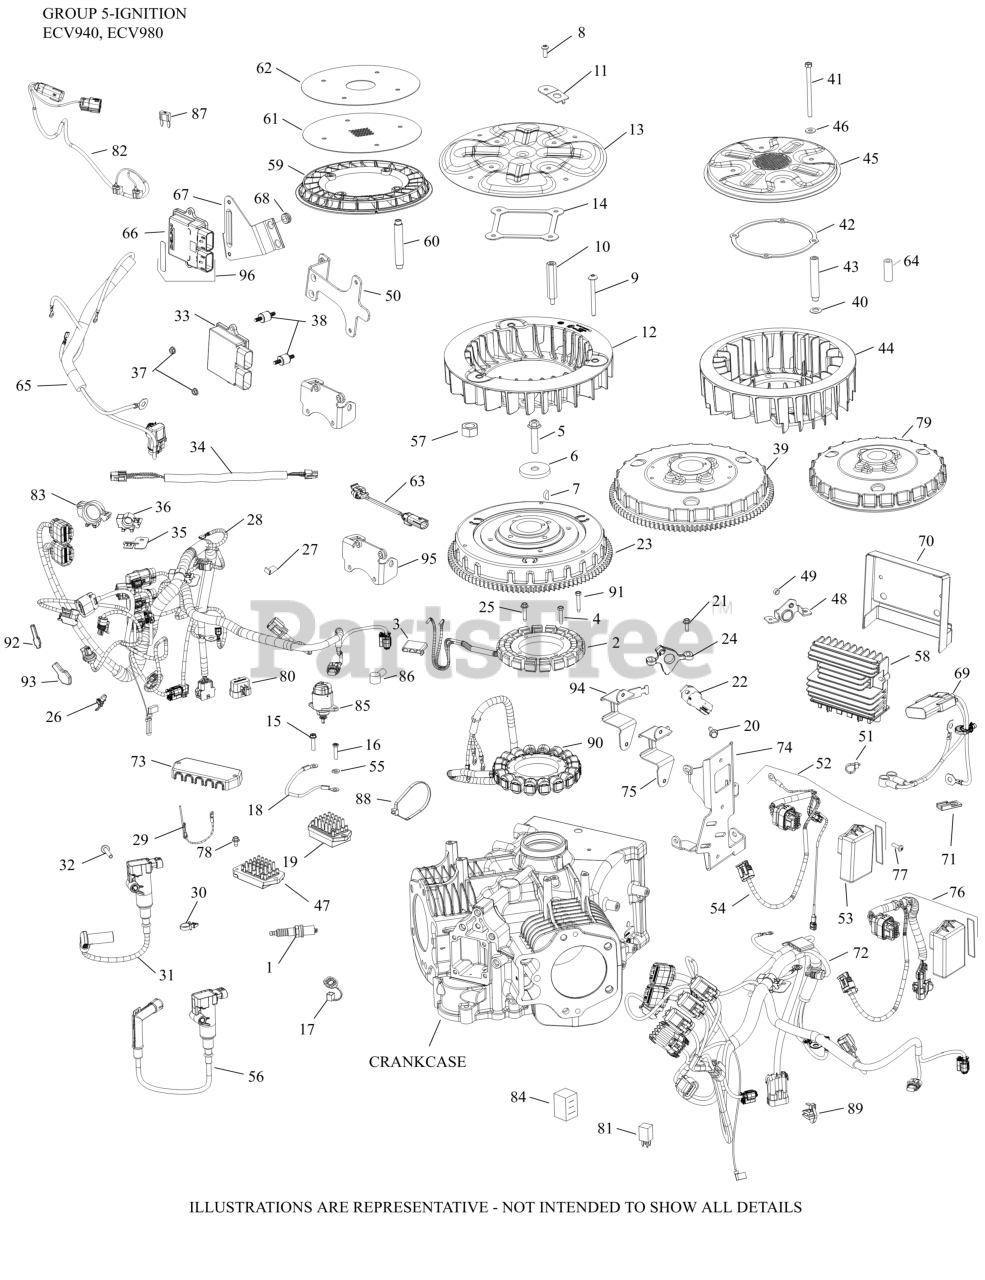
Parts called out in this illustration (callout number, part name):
1	PLUG, SPARK
2	KIT, 15 / 20 AMP STATOR
3	CONNECTOR
4	SCREW, THREAD FORMING
5	SCREW, FLG M10X1.5X45-USE 25 086 361-S
6	WASHER, FLAT 13/32"
7	KEY, 3/16" X 5/8"
9	SCREW, TRS HD M6X1.0X65
10	STUD, GRASS SCREEN
11	PLATE, GRASS SCREEN WASHER
12	KIT, FAN AND SPACERS
13	KIT, GRASS SCREEN
14	STIFFENER, GRASS SCREEN
15	SCREW, HEX FLANGE HI-LO
17	CAP, CONNECTOR
18	KIT, GROUND, LEAD
20	SCREW, THREAD FORMING
21	SCREW, THREAD FORMING
22	SENSOR, SPEED
23	FLYWHEEL ASSEMBLY
24	BRACKET, SENSOR SPEED
25	SCREW, THREAD FORMING-USE 25 086 472-S
25	SCREW, THREAD FORMING
26	TIE, WIRE
27	CLIP, BLOWER HOUSING
28	HARNESS, WIRING ASSEMBLY - EFI
29	LEAD, OIL TEMP
31	COIL, IGNITION - EFI
32	SCREW, FLG (BLACK) M6X1.0X34
33	MODULE, ECU (ECV940)
34	HARNESS, EFI DIAGNOSTIC EXTENSION
47	REGULATOR, RECTIFIER
51	TIE, WIRE
